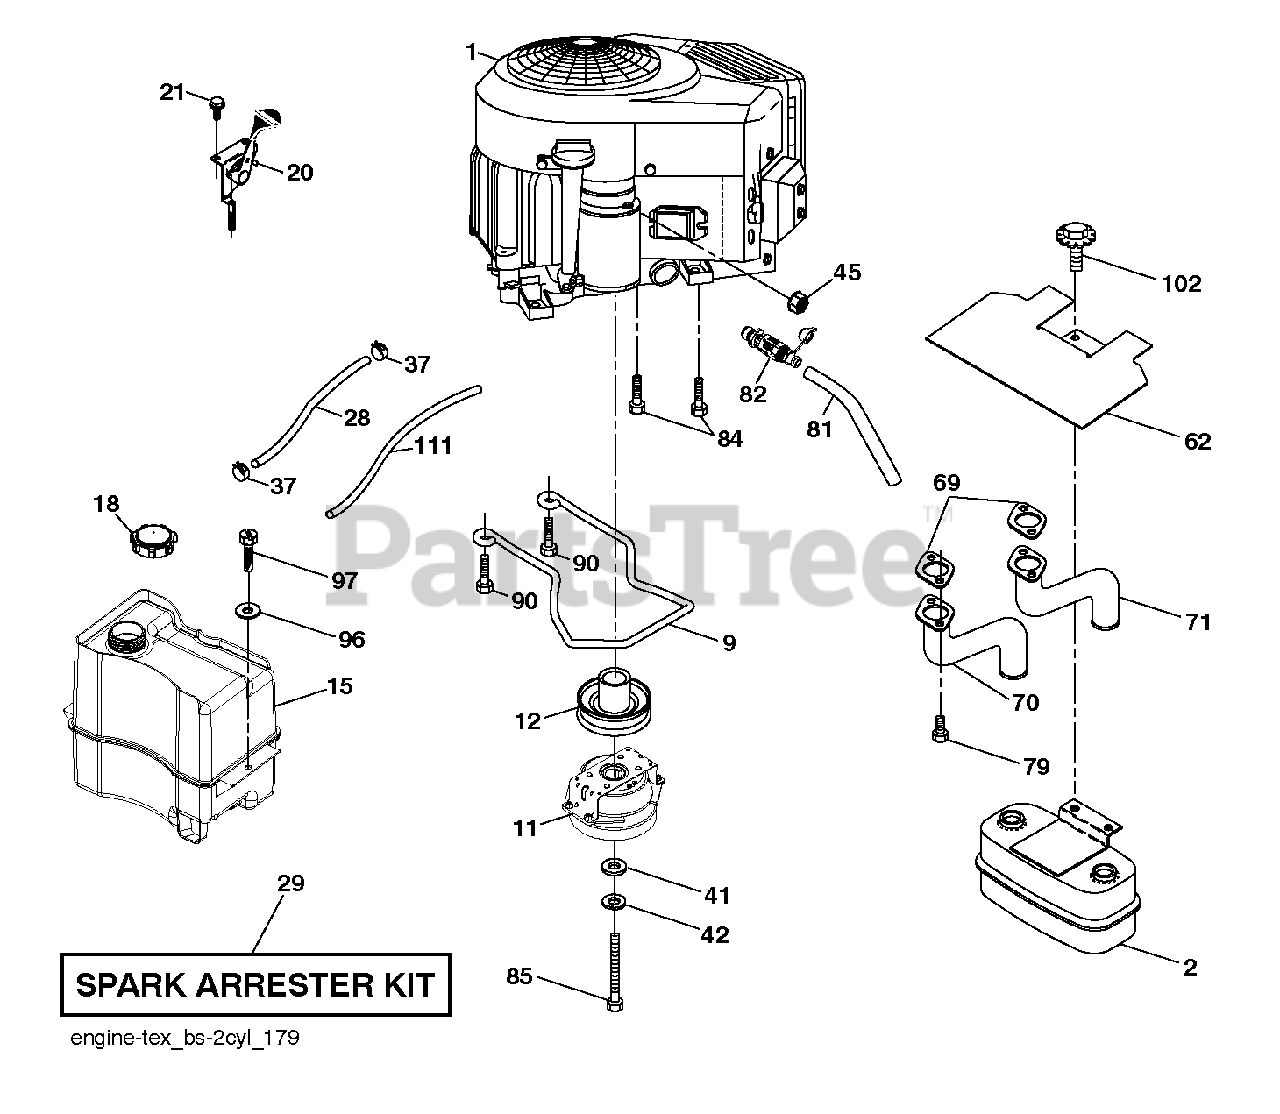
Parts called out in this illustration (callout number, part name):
2	Muffler Assembly, Twin MN
9	KEEPER.BELT.ENG.4.25"2.BLT.431
11	CLUTCH.OGURA.5.0PD.GT1.5A-EH07
12	PULLEY.ENGINE.TUFFTORQ
15	Front Tank Assembly, 2.5 Gallon
18	FUEL.CAP.ASM.2.25TETHRED.RATCH
20	THROTTLE.COBRA.38"READSTART.BK
21	SCREW.#10 X 0.750.BOS
28	LINE.FUEL.20"FRONT.EMI
29	KIT.SPARK ARRESTOR 794945 B&S
37	HOSE CLAMP
42	WASHER 7/16 LOCK
45	NUT
62	SHIELD.HEAT.MUFFLER
69	GASKET.MUFFLER
70	EXHAUST.TUBE.LH.BS/TWIN
71	EXHAUST.TUBE.RH.B&S.TWIN.INTEK
79	SCREW.SOCKET.HEAD.5/16-18
81	TUBE, DRAIN OIL ASM.
82	VALUE.OIL.DRAIN
84	SCREW.3/8-16
85	BOLT.HEX.7/16-20X3.75.GR5.RED
90	SCREW 3/8-16X1
97	SCREW HEXWSHR 1/4-20X3/4
102	SCREW
111	RP PURGE LINE
